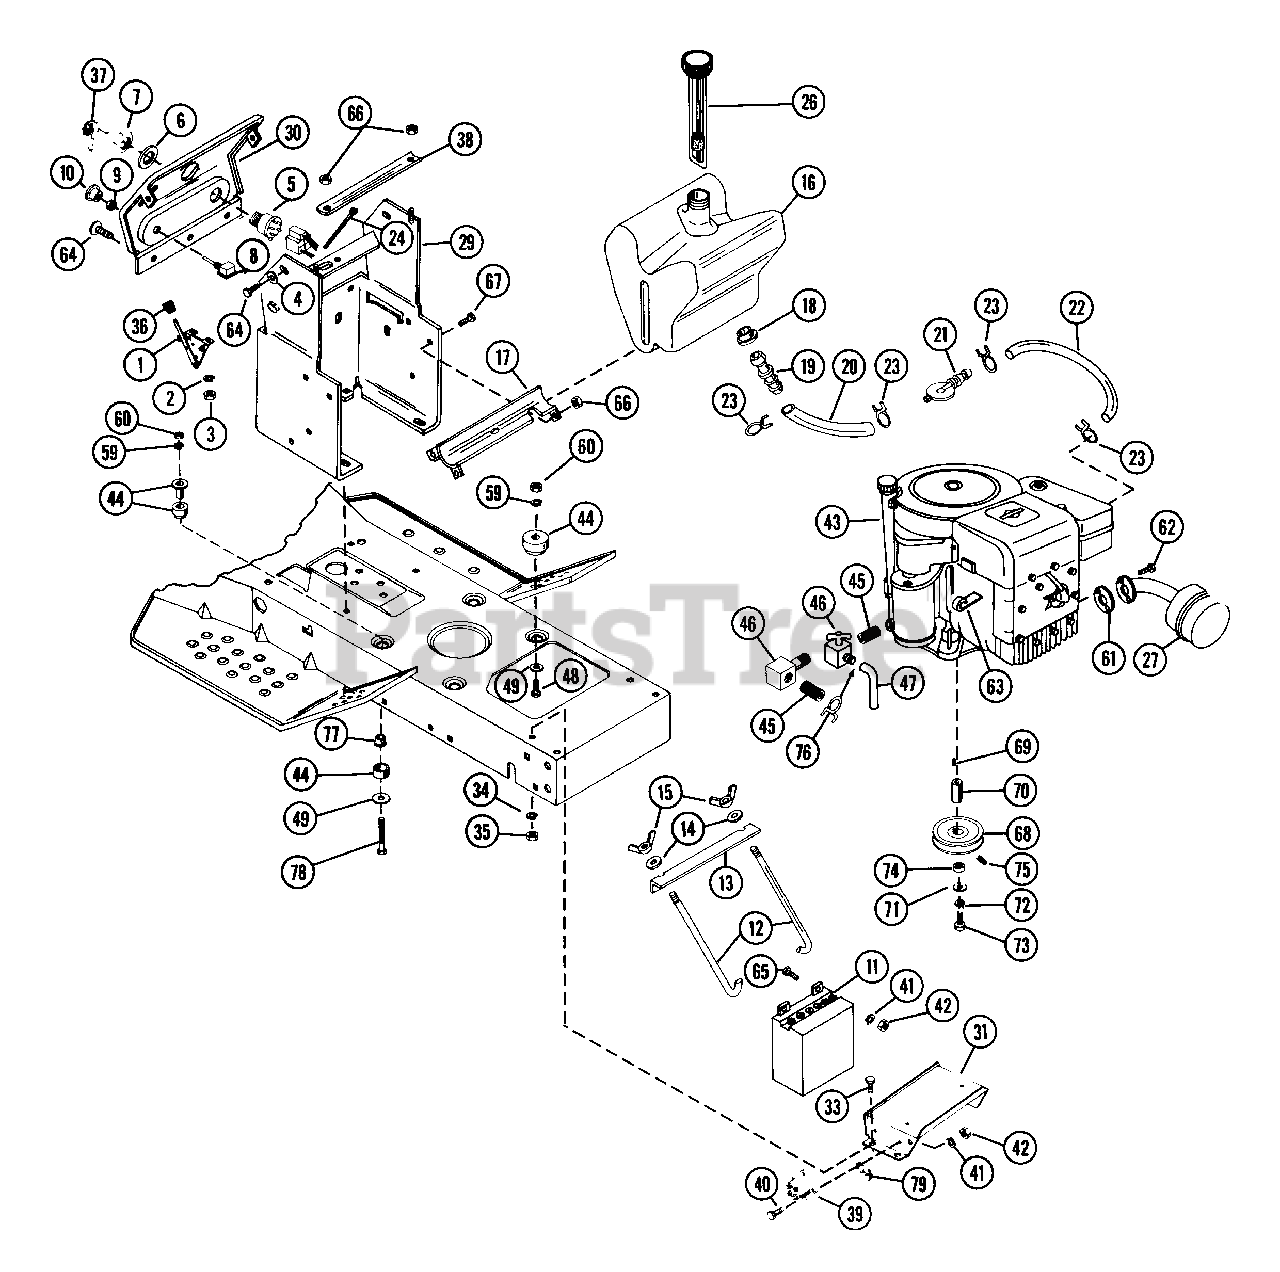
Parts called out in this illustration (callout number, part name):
1	THROTTLE CONTROL
2	WSHR-LK 10X.047 MED PL
3	NUT-HEX 10-24 PL
4	WSHR-FL-STL .250X.562X.049 PL
5	IGNITION SWITCH
6	WSHR-LK-INT .563X.040 PL
7	NUT .562-24
8	LIGHT SWITCH
9	NUT .50-20 PL
11	BATTERY
12	HOOK BOLT
13	BATTERY HOLD DOWN
14	WSHR-FL-STL.312X.734X.065PL
15	NUT-WING .250-20 YWZC
16	FUEL TANK
17	LOWER TANK SUPPORT
18	FUEL TANK GROMMET
19	GAS LINE FITTING
20	HOSE (SERV. ONLY)
21	FUEL FILTER
22	HOSE (SERV. ONLY)
23	CLAMP-HOSE WIR.490/.510X.092#8
24	TIE DOWN
26	FUEL GAUGE
27	EXHAUST MUFFLER
29	DASH BASE WITH DECALS
30	DASH WITH DECALS
31	BATTERY STAND
32	FRAME W/DECALS
33	BLT-HEX .31-18X.50 PL GR2
34	WSHR-LK .312X.097 PL HVY
35	NUT-HEX .312-18
37	KEYS
38	CLAMP STRAP
39	SOLENOID
40	BLT-HEX .25-20X.50 PL GR2
41	WSHR-LK .250X.077 HVY PL
42	NUT-HEX .250-20 PL
43	10 H P TECUMSEH ENGINE
44	ISOLATION MOUNTING
46	PIPE FITTING 90 DEG. X 3/8 ELB
48	BLT-HEX .31-18X2.50 PL GR2
49	WSHR-FL-STL .312X1.62X.13
59	WSHR-LK .312X.097 PL HVY
60	NUT-HEX .312-18
63	J-CLAMP
64	SCR-TAP 10-16X.50 HWH PL AB
65	BLT-HEX .25-20X.75 PL GR2
66	NUT-LK TOP .250-20 PL
67	BLT-HEX .25-20X.50 PL GR2
68	PLY-? 3.50X1.0
69	KEY-SQ .25X1.0X.25 SAE 8630
70	BEARING SPACER 1.032X1.25X1.78
71	WSHR-FL-STL .469X1.380X.125
72	WSHR-LK .438X.133 HVY
73	BLT-HEX .44-20X1.00 GR5
74	SPACER 1.032X1.250X.312
75	SCR-SET .32-18X.25 SKHCUP OH
77	RUBBER BUSHING
78	BLT-HEX .31-18X2.25 PL GR2
